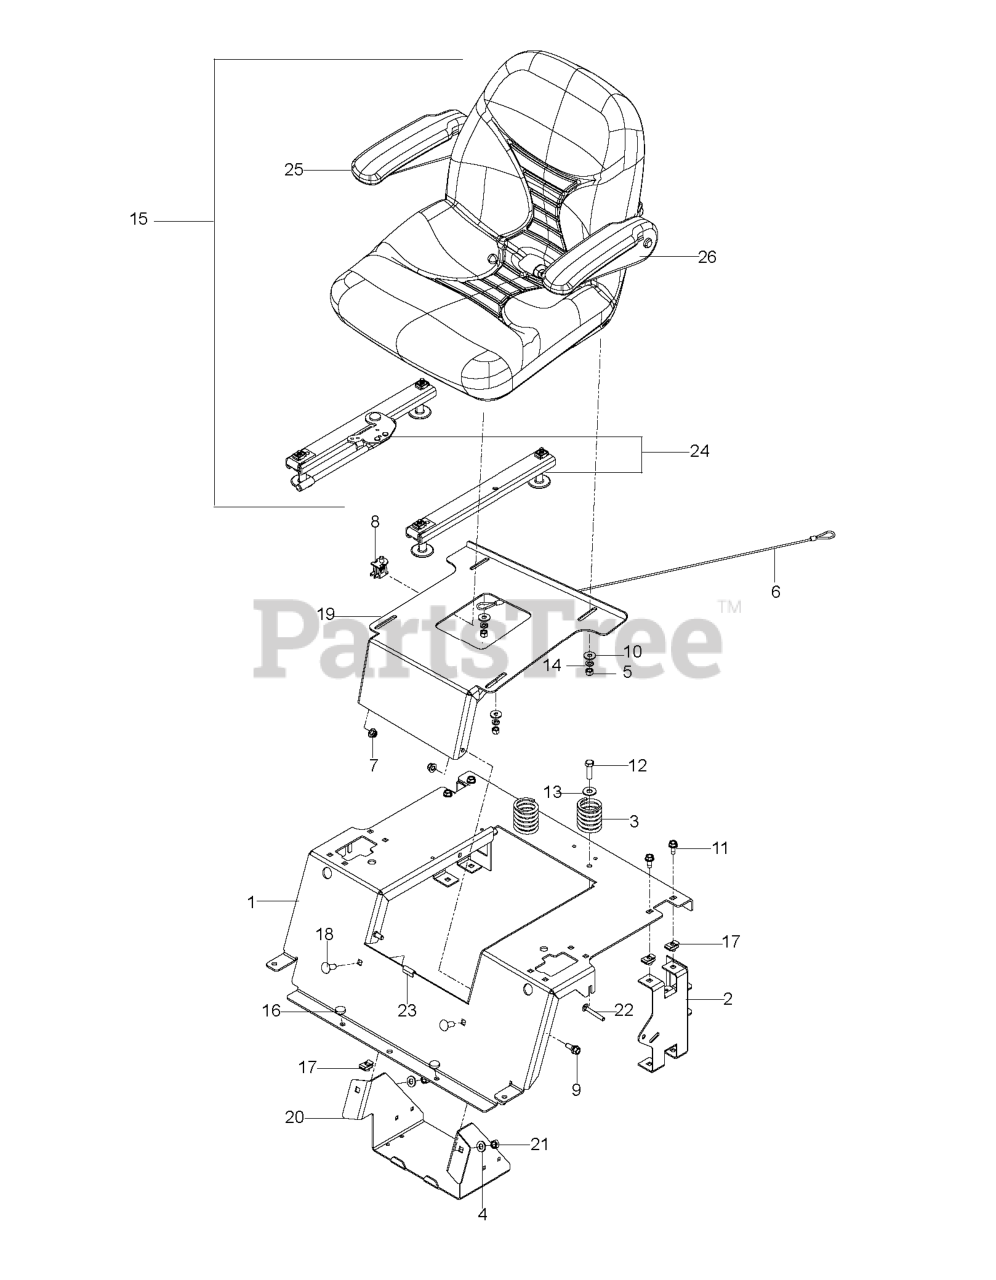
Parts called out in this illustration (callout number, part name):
1	SUPPORT, SEAT, FLAT ORANGE
2	SUPPORT, REAR SEAT, BLACK
3	SPRING, SEAT
4	WASHER 3/8 SAE FLAT
5	NUT 5/16 NYLOC
6	SEAT LANYARD
7	5/16-18 NYLOC FLANGE NUT
8	SEAT SWITCH
9	SB 5/16-18 HEX HD GD5, BLK ZN
10	WASHER 5/16 FLAT
11	BOLT 5/16-18 X 3/4
12	HCS 3/8C X 1 1/4 GR5
13	WASHER 3/8 FLAT
14	WASHER.LOCK.HVY.HLCL.SPR.5/16
15	SEAT
16	GROMMET, BUMPER
17	U-CLIP 5/16-18 NUT RETAINER
18	RHSNB 3/8C X 1
19	PAN, SEAT, ORG
20	BOX, BATTERY, BLACK
21	NUT 3/8-16 NYLOC
22	RHSNB 5/16-18 X 2-1/2 GR5 ZD
24	TRACK ADJUSTMENT KIT
25	ARMREST KIT, RT SQUARE END
26	ARMREST KIT, LT SQUARE END
